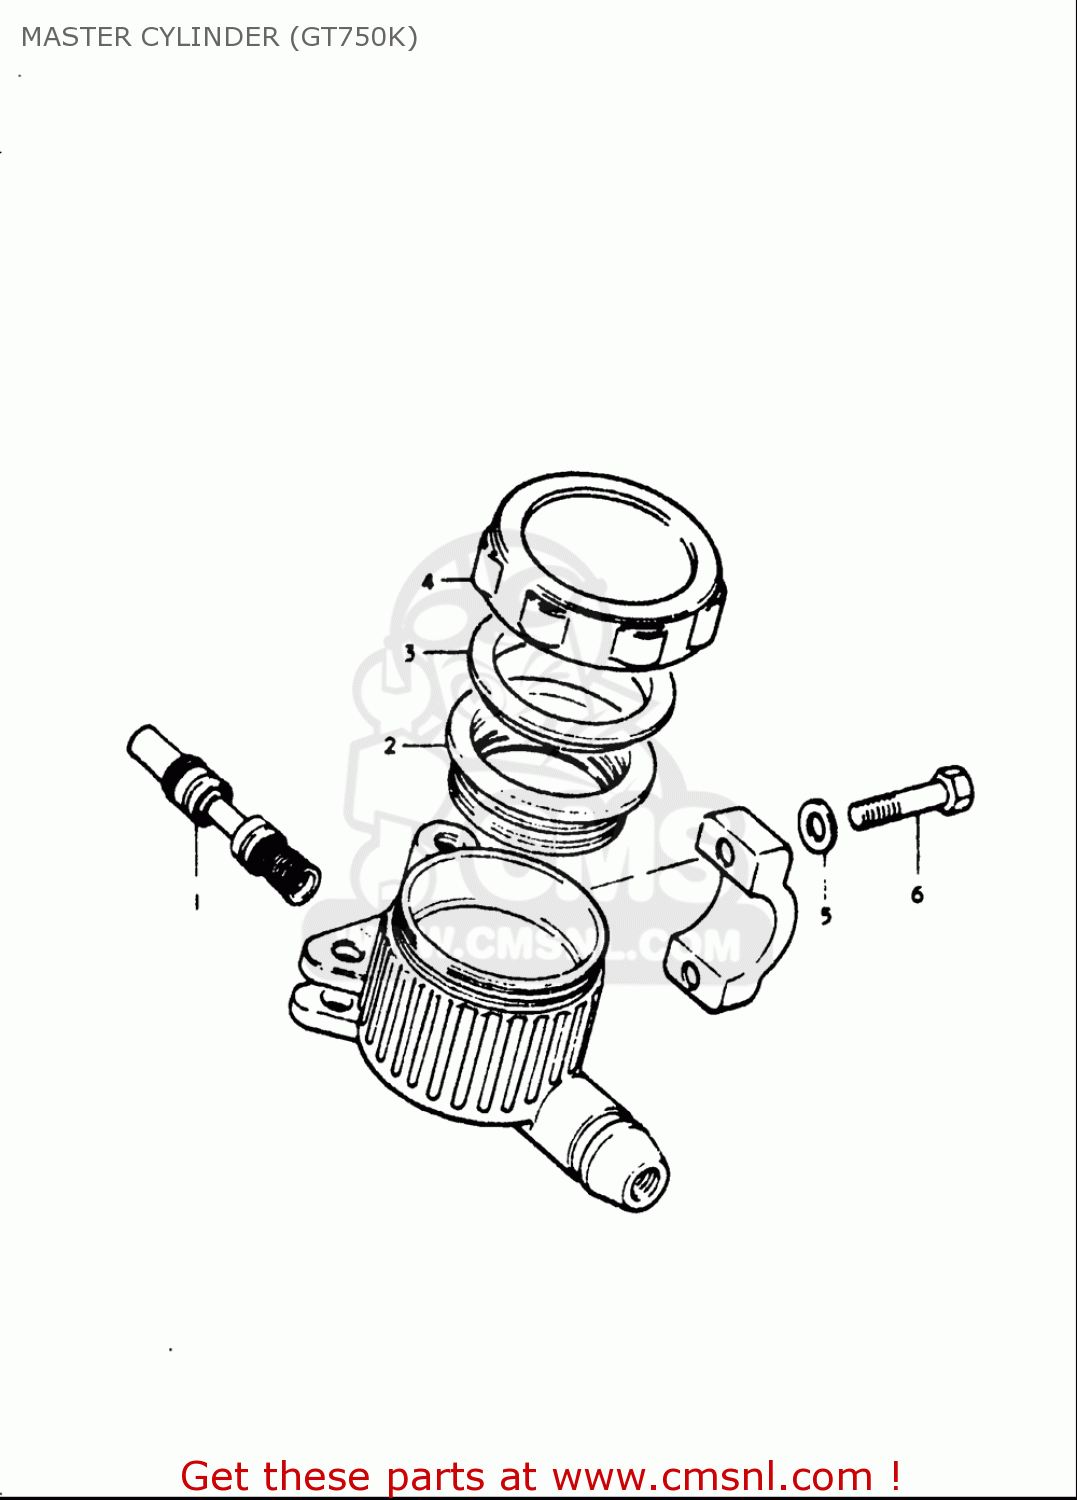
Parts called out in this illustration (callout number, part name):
1	PISTON & CUP SET
2	DIAPHRAGM
5	WASHER
6	BOLT
